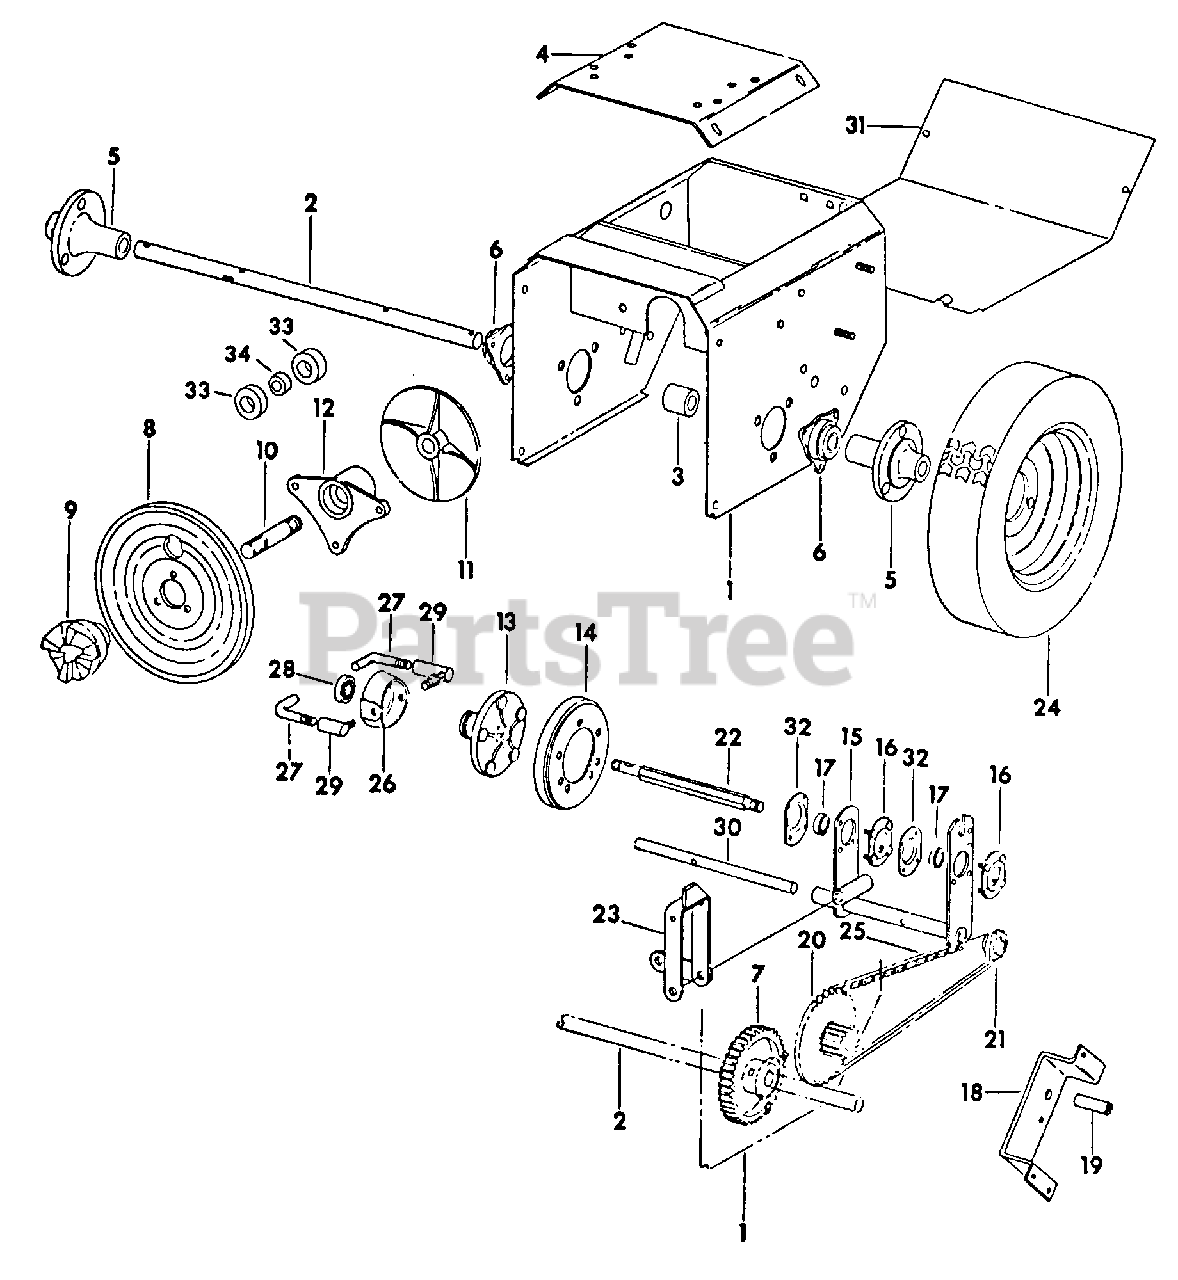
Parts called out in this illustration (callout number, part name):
1	HOUSING. MAIN DRIVE
2	AXLE
3	SPACER, AXLE
5	HUB, WHEEL
5	BRACKET, WHEEL MTG
6	BEARING, FLANGE AXLE
6	FLANGE, AXLE BRG
7	GEAR, SPUR 40 TEETH
10	SHAFT, DRIVEN
12	HOUSING, BEARING
13	HUB, DRIVEN DISC
14	WHEEL, FRICTION
15	BRACKET, DRIVE
16	RETAINER, BRG
17	BEARING, BALL
18	BRACKET, TRANSFER
20	SPROCKET, SPUR GEAR
21	SPROCKET 9 TEETH
23	BRACKET, SHIFTING
24	WHEEL W/TIRE ASSY
25	CHAIN, ROLLER
28	BEARING, BALL
29	JOINT, 1/4-28 BALL
30	SHAFT, PIVOT
31	PLATE, BOTTOM GUARD
32	RETAINER, BRG
33	BEARING, BALL
34	SPACER, BEARING
IH-102581	SCREW, 5/16-18 X 3/8 HDLS HEX-SOC-HD CUP-PT SET
